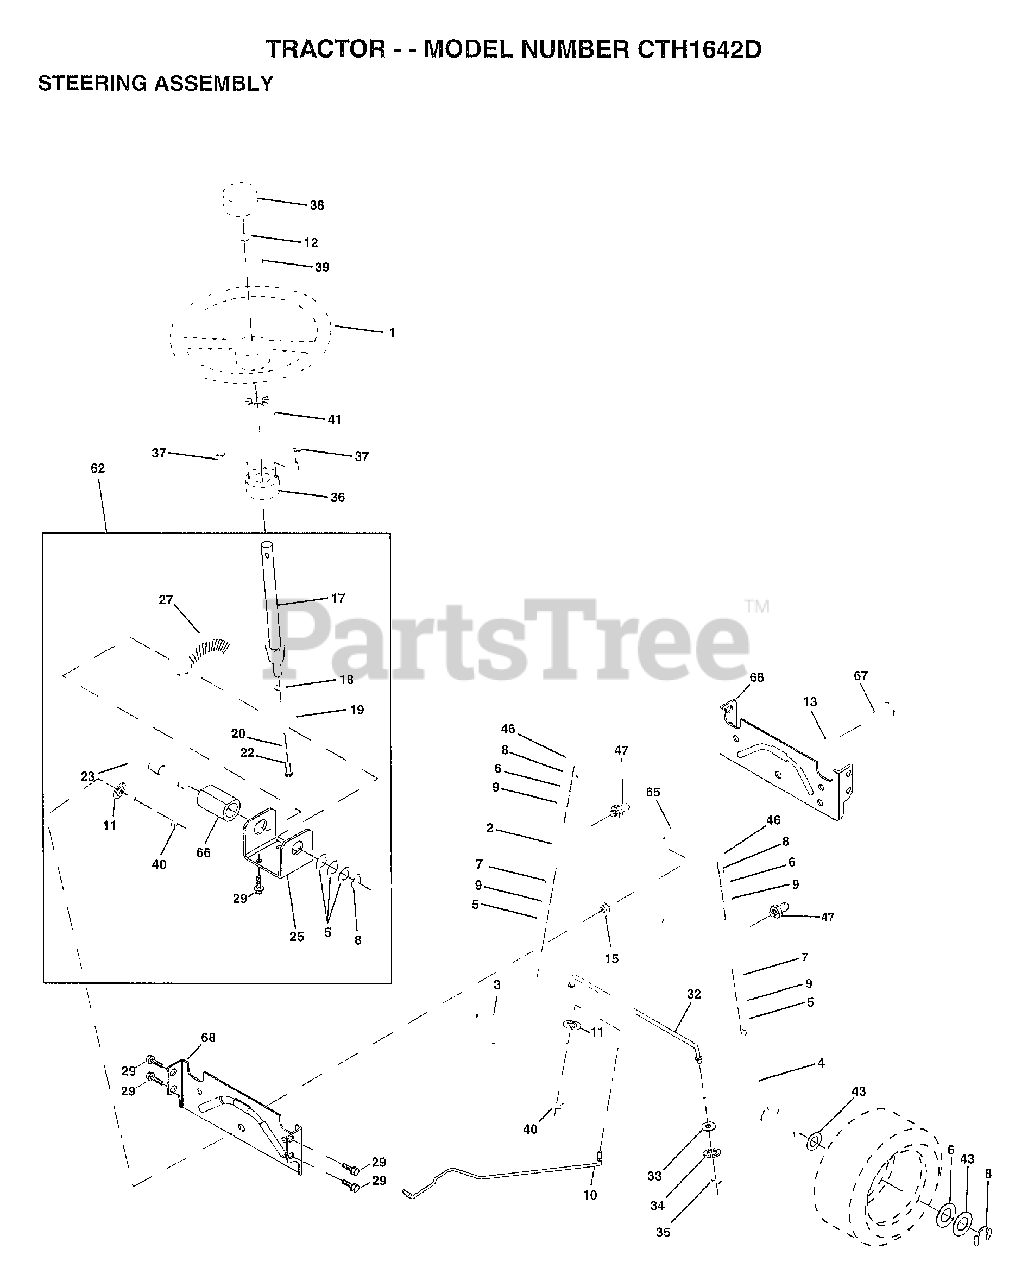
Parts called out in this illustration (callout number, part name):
1	WHEEL STR AYP BLK
2	AXLE ASM
5	WASHER .T
6	WASHER
7	WASHER
8	RING
9	COL. SRTG. BEAR.
10	DRAGLINK-STAMPED
11	LOCKWASHER
13	BEARING AXLE
15	"NUT-LOC,FLANGE LT"
17	SHAFT ASM STEERNG
18	THRUST WASHER
19	SUPPORT.SHAFT
22	SCREW HEX SOC1/4-
25	BRKT-STEERING
27	GEAR SECTOR
29	SCREW
32	ROD.TIE.19.75
33	WASHER M
34	LOCKWASHER
35	NUT.LOCK.5/16-24
36	BUSHING.STRG.3/4
37	"SCREW-TT,10-32 FL"
38	CAP STEER AYP
39	WASHER
40	GRIPCO NUT
41	ADAPTER LT
43	WASHER
46	CAP
47	ZERK M
62	KIT STEERING ASM
65	SPACER AXLE
66	"BEARING-ARM,PITMA"
67	BOLT
68	BRACE AXLE
